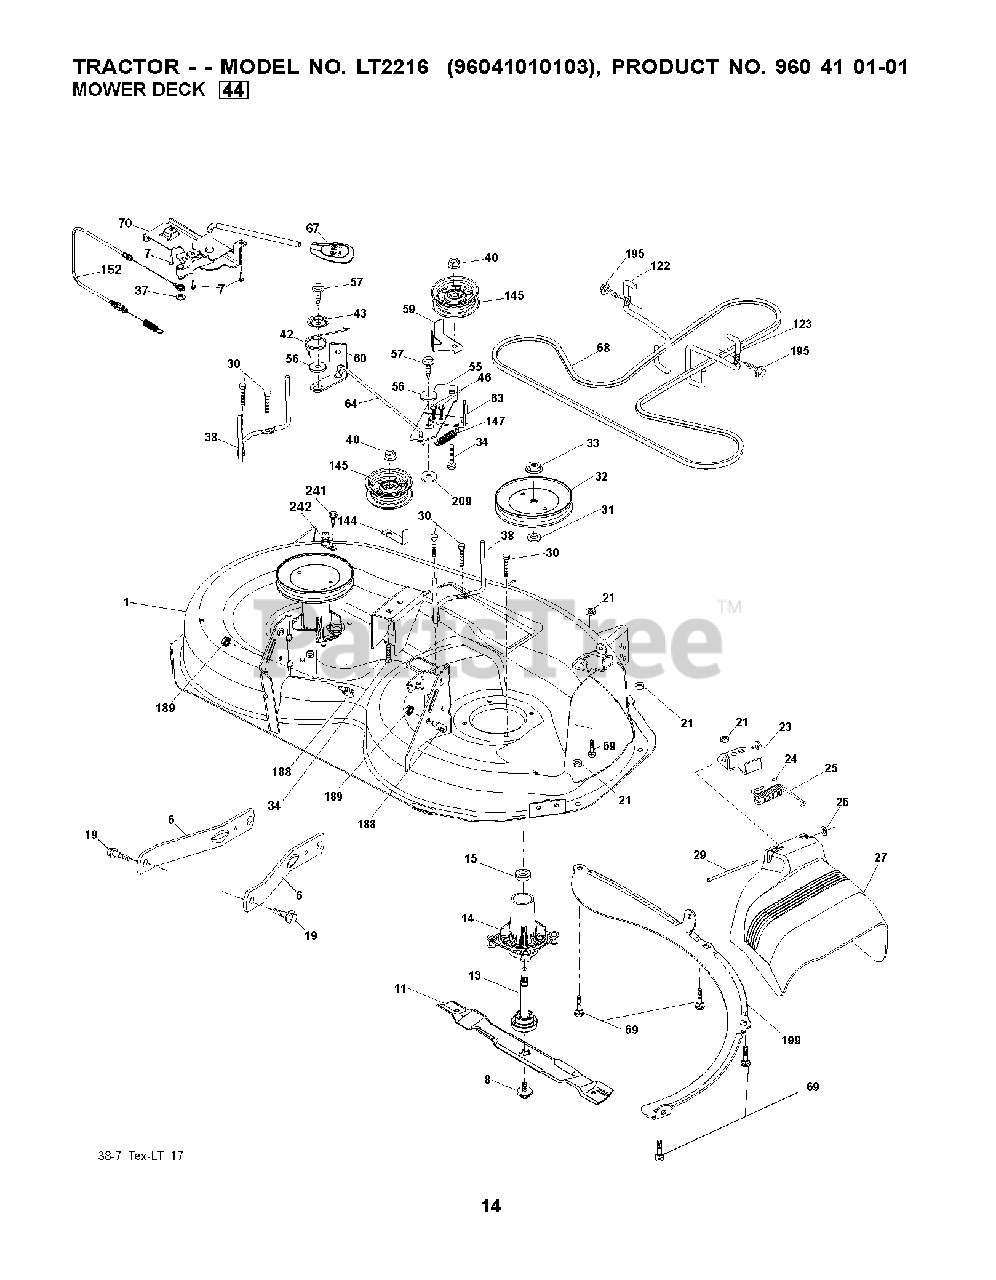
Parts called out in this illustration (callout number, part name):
6	ARM.SUSPENSION.MOWER.R
7	SCREW.#10 X 0.750.BOS THREAD
8	BOLT.WASHER.ASM.7/16-2
11	BLADE 38" PREMIUM
13	SHAFT.ASM.MDRL.N/GREASE.38
14	HOUSING MANDREL
19	BOLT.SHOULDER
21	LOCKNUT
23	BRKT.DEFLECTOR.38"2005+
24	CAP-SLEEVE LT
25	SPRING.TORSION.DEFLECT
26	NUT PUSH M
29	ROD.HINGE
30	SCREW, WASHER HEAD
31	WASHER.SPACER.MANDREL
32	PULLEY.MANDREL.5.0.PD.38"
33	NUT.FLANGE.LOCK.TOP
34	BOLT.3/8-16X1.50
38	KEEPER BELT LH MANDREL
40	NUT LOCK FLG 3/8-16 UNC
42	SPRING.TORSION.BRAKE
43	SRPING.TORSION.RETAINE
46	SCREW.1/4-20X5/8
55	IDLER.ARM
56	SPACER.RETAINER
57	SCREW 3/8-16X1
59	GUARD, BELT
60	ARM BRAKE MOWER RH 38"
63	ARM BRAKE MOWER RH
64	LINK BRAKE
67	HANDLE.CLUTCH.CABLE.LT
69	BOLT
70	CLUTCH.ASM.MANUAL.LT.PRED
122	KEEPER BELT ENGINE LH
123	KEEPER BELT RH
144	KEEPER BELT
145	PULLEY.IDLER.48"PRIMARY
147	SPRING RETURN
152	CABLE.CLUTCH.MANUAL.
188	STUD.FASTNER.W/ANTI-ROTATE
189	NUT LOCK HEX FLANGE 5/16-18
195	SCREW, 3/8-16X3/4
199	BAFFLE VORTEX
209	WASHER 12/32X2X10GA
242	PORT.WASHOUT
